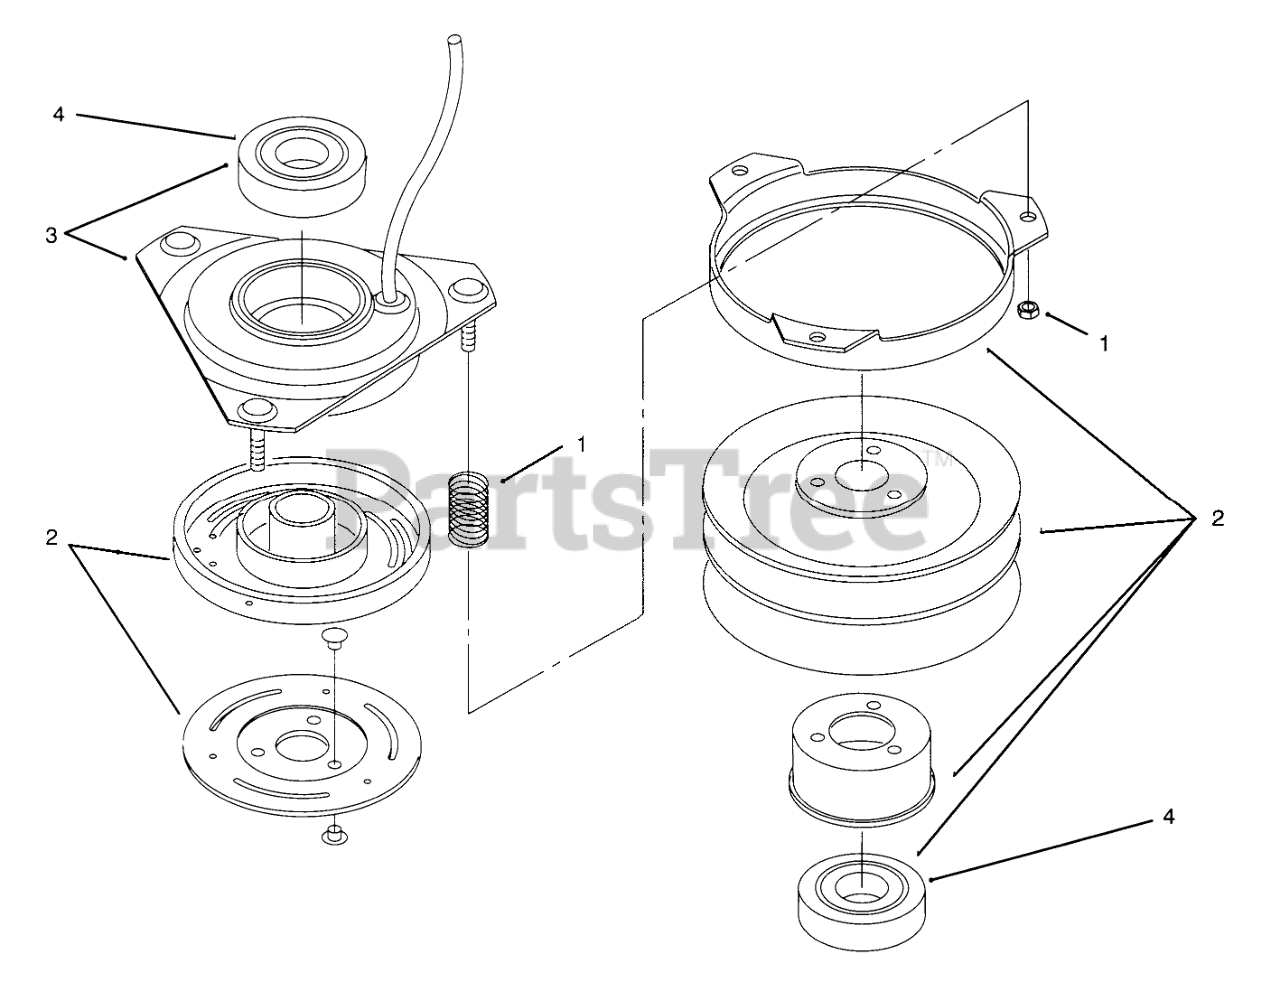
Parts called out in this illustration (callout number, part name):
1	ACCESSORY PKG SRVC PART
2	ROTOR & ARMATURE ASSY
3	FIELD ASSY (SRVC PART)
4	BEARING-ELEC CLUTCH
